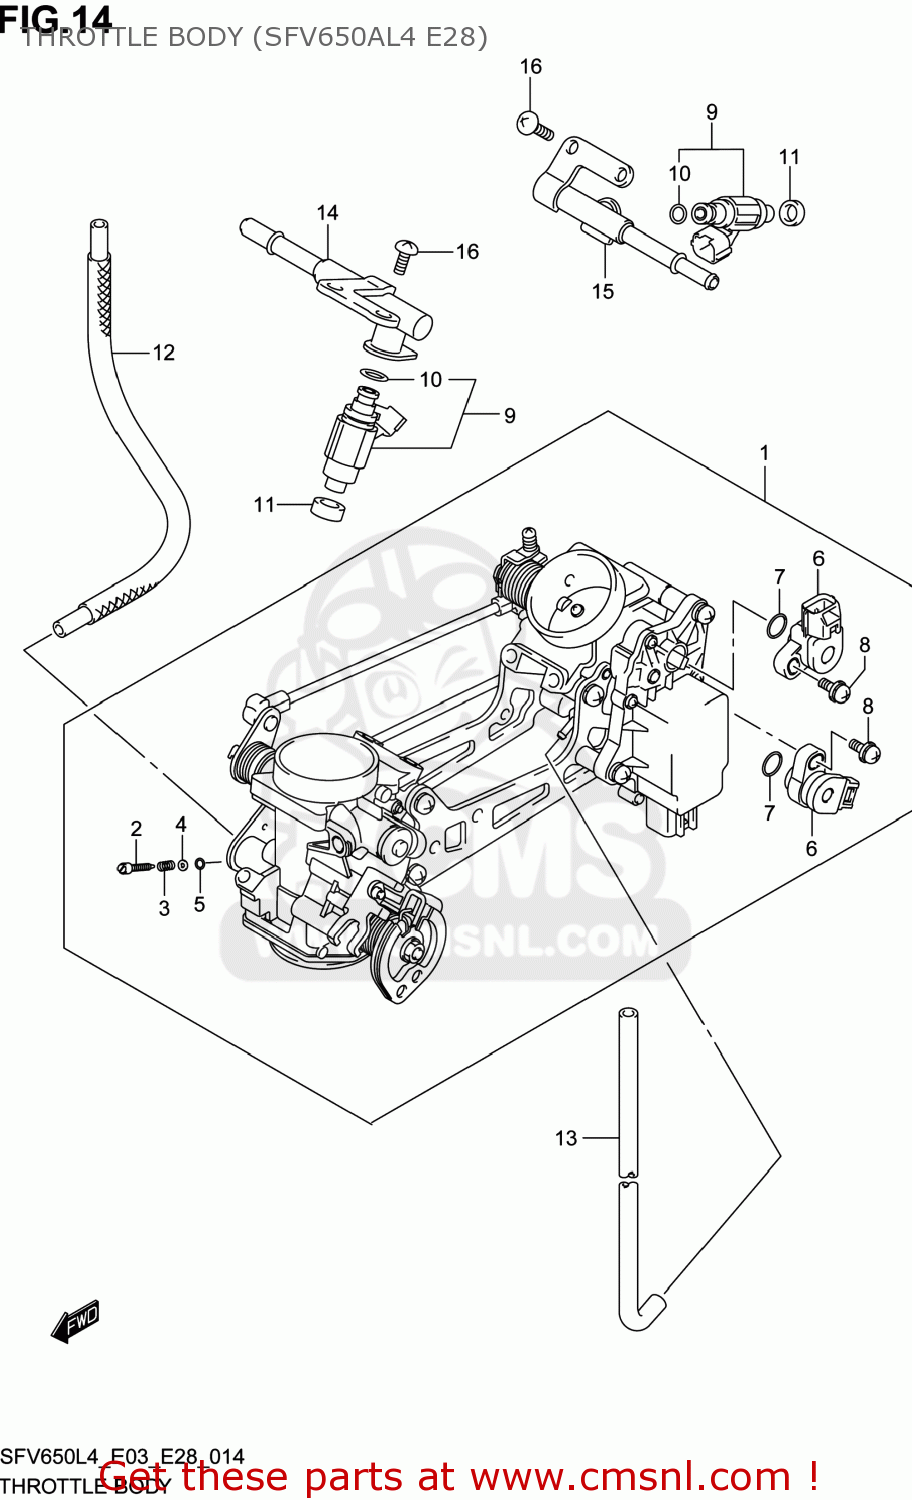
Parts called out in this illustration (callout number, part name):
1	BODY ASSY,THROTTLE
2	SCREW
3	SPRING,THROTTLE SCREW
4	WASHER
5	O RING,PILOT AIR SCREW
6	SENSOR
7	O RING
8	SCREW
9	INJECTOR ASSY
10	O-RING
11	SEAL
12	HOSE
13	HOSE
14	DELIVERY PIPE
15	DELIVERY PIPE
16	SCREW
